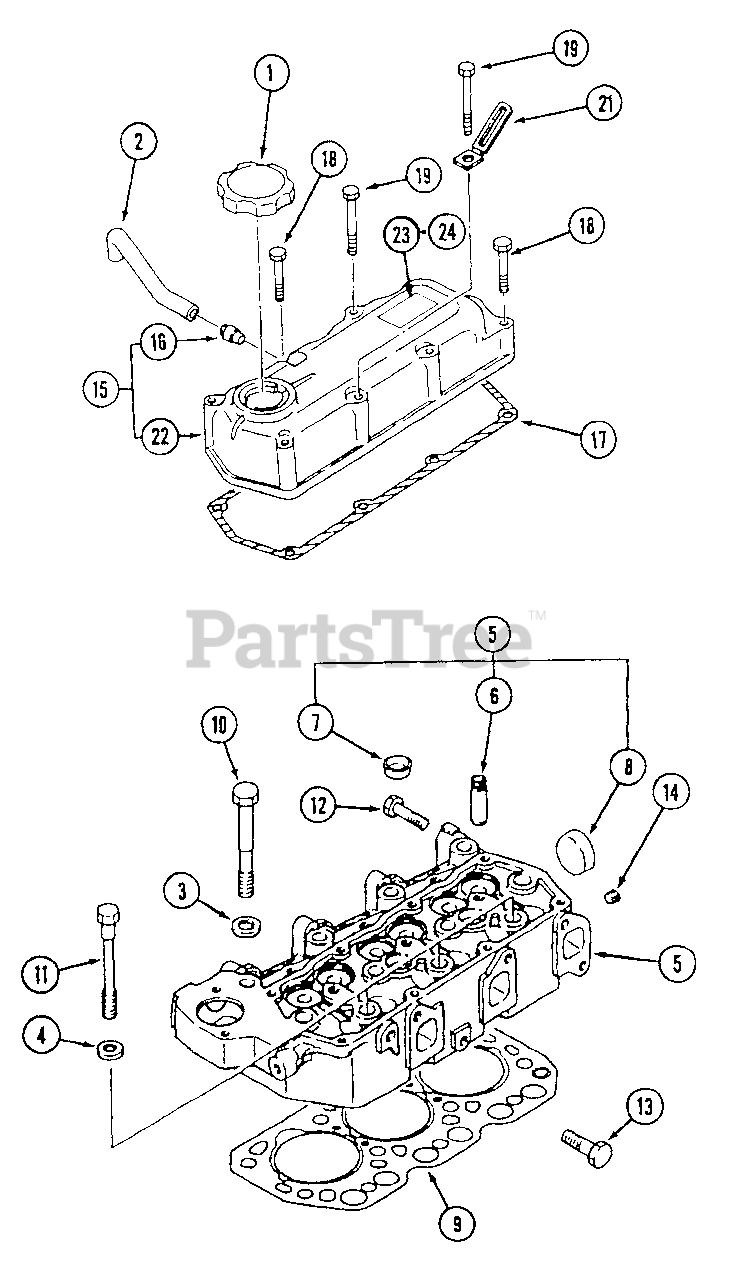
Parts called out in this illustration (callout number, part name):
1	Cap, Oil Filler
2	Pipe, Air Breather
5	Head Ass'y., Cylinder
6	Guide, Valve
7	Cap, Sealing
8	Cap, Sealing
9	Gasket, Cylinder Head
10	Bolt, Cylinder Head
11	Bolt, Cylinder Head
14	Plug, Taper
15	Cover Ass'y.,Rocker
16	Pipe
17	Gasket, Rocker Cover
22	Cover, Rocker
23	Label, Model
